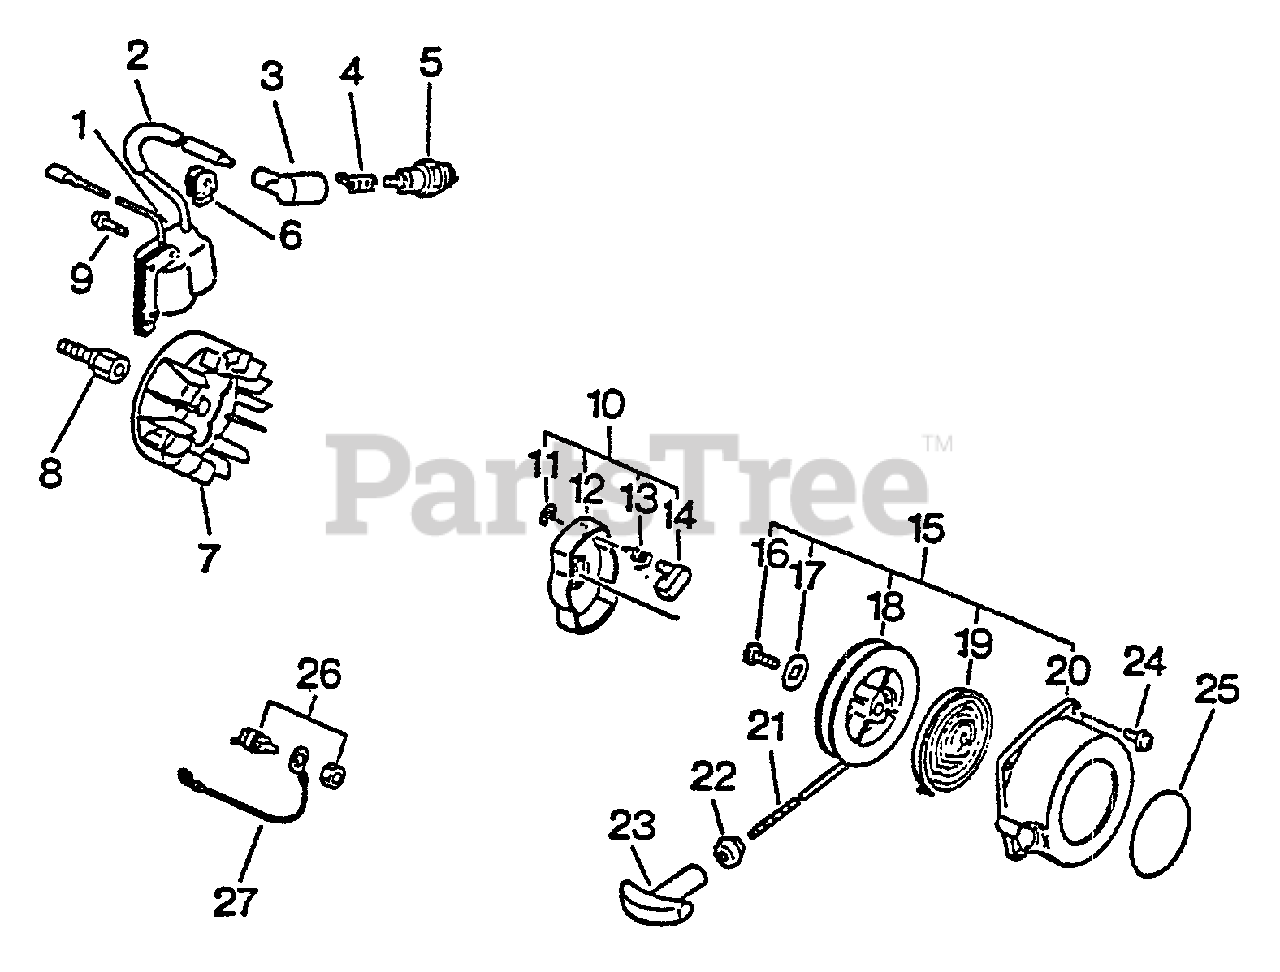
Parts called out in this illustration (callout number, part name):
1	COIL, IGNITION
3	CAP, SPARK PLUG
4	TERMINAL, SPARK PLUG
5	SPARK PLUG - BPM7A
5	SPARK PLUG - BPMR7A
7	FLYWHEEL
8	HUB, FAN
9	SCREW 4×22
10	STARTER PAWL ASSY
11	E-RING 4
12	CATCHER, PAWL
13	SPRING, RETURN
14	PAWL, STARTER
15	STARTER ASSY
17	WASHER
18	REEL, ROPE
19	SPRING, RECOIL
20	CASE, RECOIL STARTER
21	ROPE, STARTER
22	GUIDE, ROPE
23	GRIP, STARTER
24	SCREW 4×18
25	LABEL, ECHO
26	SWITCH, ON-OFF
27	LEAD - GROUND
